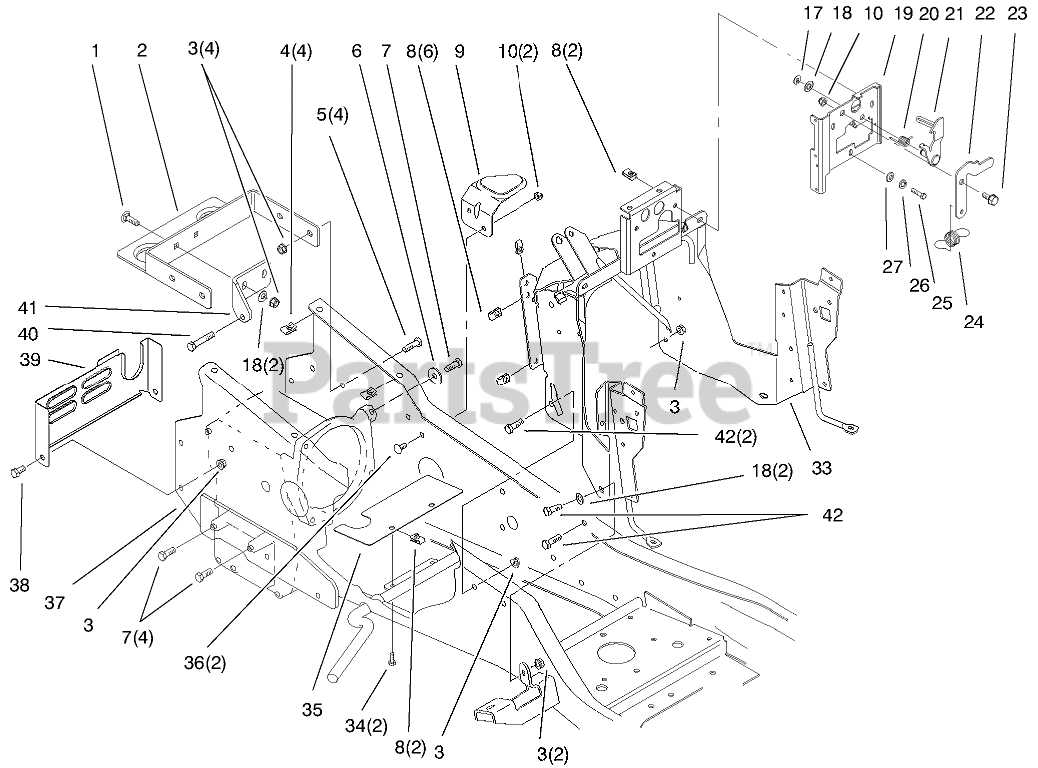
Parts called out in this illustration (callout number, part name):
1	BOLT-CARR
2	Support-Gas Tank
3	NUT-LOCK, NI
4	NUT-U
5	SCREW-HH
6	WASHER
7	SCREW-HH, LOCK
9	SUPPORT-TANK, FUEL
10	NUT-LOCK, NI
17	RING-RETAINING
18	WASHER-FLAT
19	BRACKET-LATCH
20	SPRING-LEVER, LATCH
21	LEVER-LATCH
22	LATCH-LEVER, TENSION
23	BOLT-SHOULDER
24	SPRING-LEVER, LATCH
25	SCREW-HH
26	WASHER-LOCK
27	WASHER-FLAT
33	WA-TOWER
34	SCREW-HH
35	BAFFLE-FAN
36	BOLT-CARR
37	Frame
38	SCREW-HH
39	COVER-REAR
40	SCREW-HH W/LOCTITE
41	Strap-Torque
42	SCREW-HH
